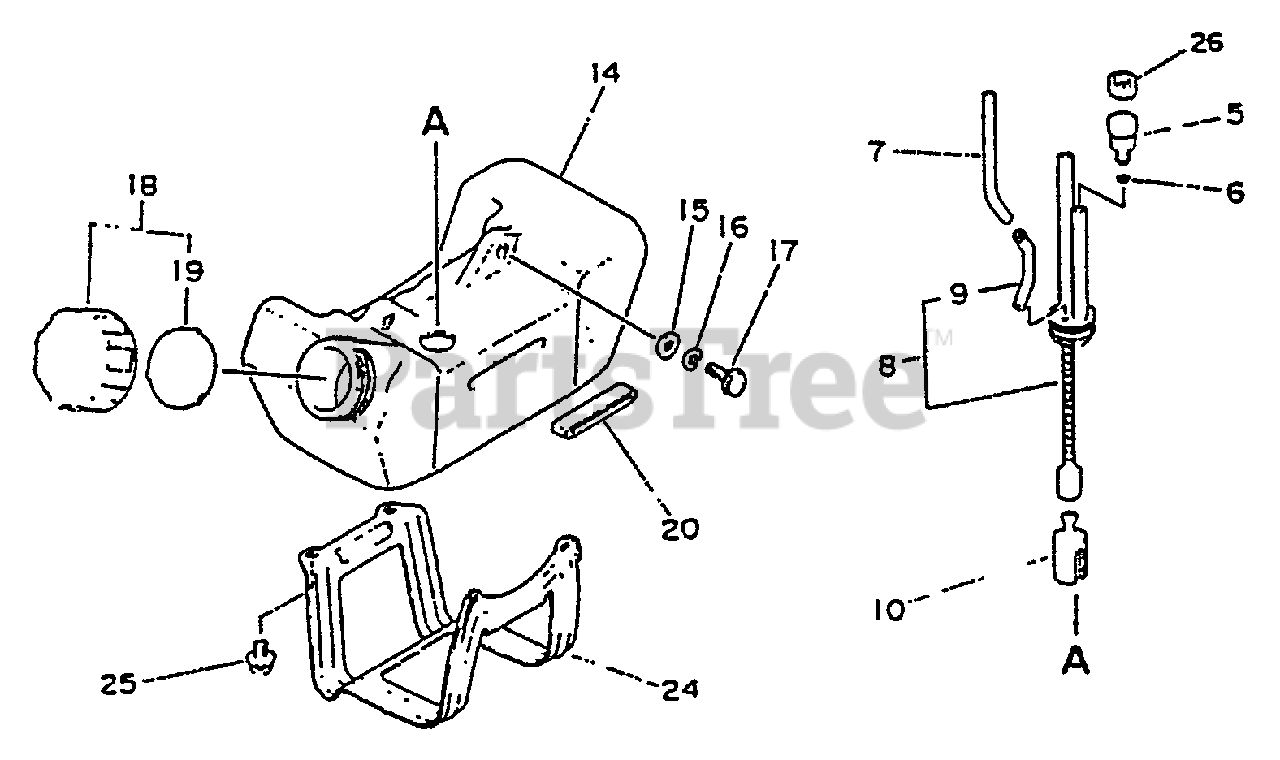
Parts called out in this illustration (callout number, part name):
5	VENT, FUEL TANK
6	CLIP - 5.5
7	PIPE - 3X6X75 -- CLEAR
8	FUEL PIPE KIT
9	CONNECTOR, PIPE
10	FILTER, FUEL
14	TANK, FUEL
15	WASHER - 5
16	LOCKWASHER - 5
17	SCREW - 5X16
18	CAP ASSY
19	GASKET, CAP
20	CUSHION, FUEL TANK
24	GUARD, FUEL TANK
25	SCREW - 5X10
26	COVER, VENT
